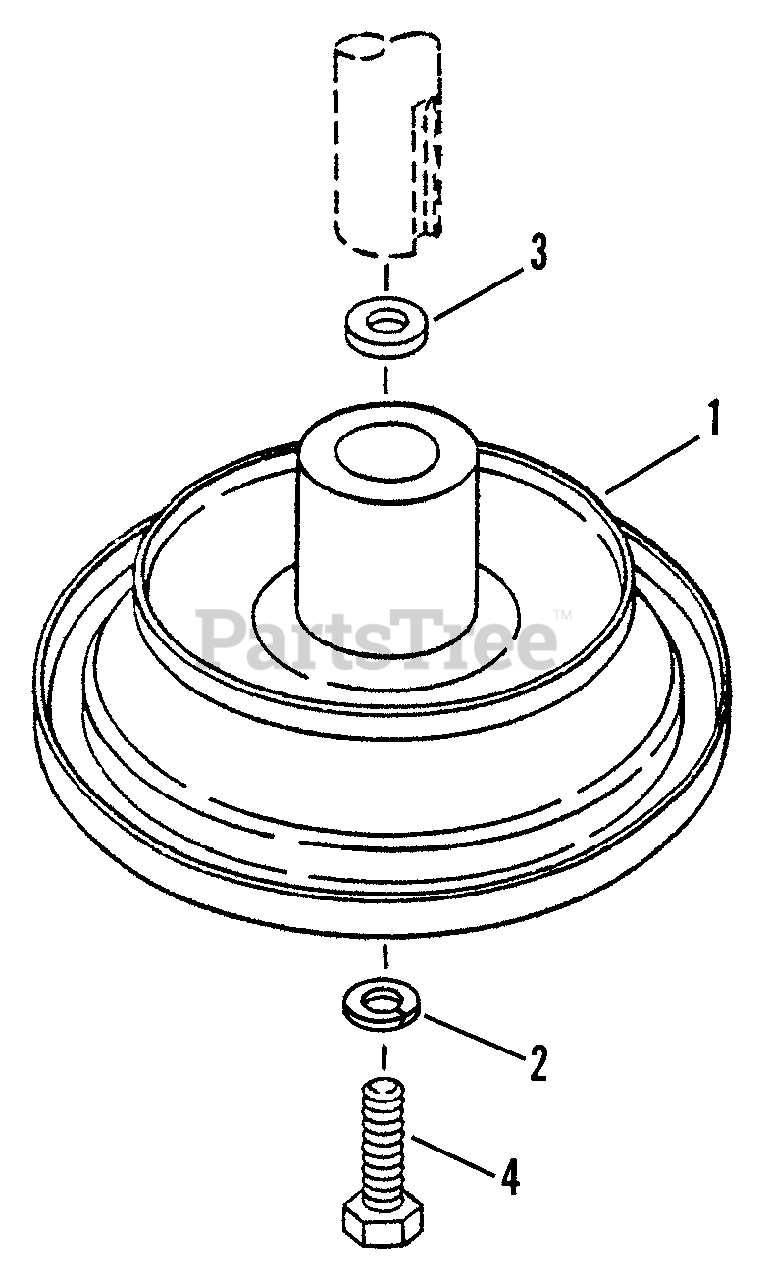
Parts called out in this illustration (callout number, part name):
1	ASSEMBLY, Drive Disc
2	WASHER, 7/16 Split Lock
3	SPACER (16HP Engines)
4	SCREW, 7/16-20 x 1" Hex Head Cap (B.& S. Engines)
